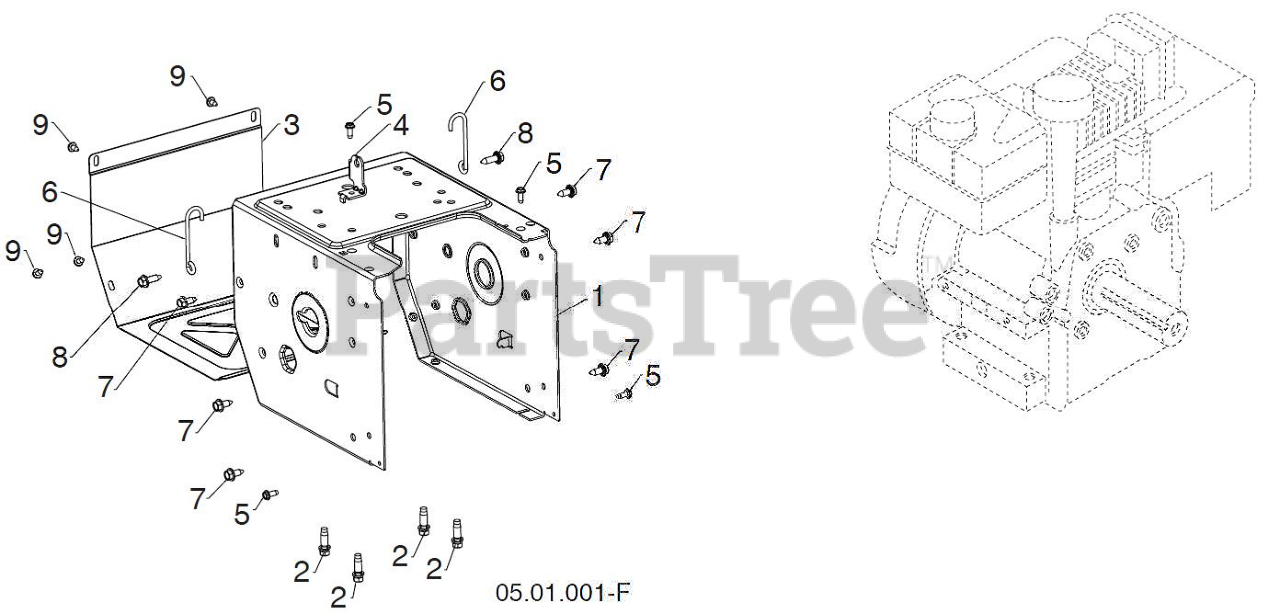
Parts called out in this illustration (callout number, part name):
1	FRAME.GEAR.CASE.ORANGE
2	BOLT 3/8-16X1-1/8
3	COVER COVER.FRAME MS668 ORANGE
4	BRACKET.SHIFTER.BZP
5	SCREW 14-20 X 5/8
6	WIREFORM.SUPPORT.CABLE
7	BOLT.HEX.HD.WASHER.5/16-18X.75
8	SCREW HEX_SERR_HD_5_16-18X1.0
